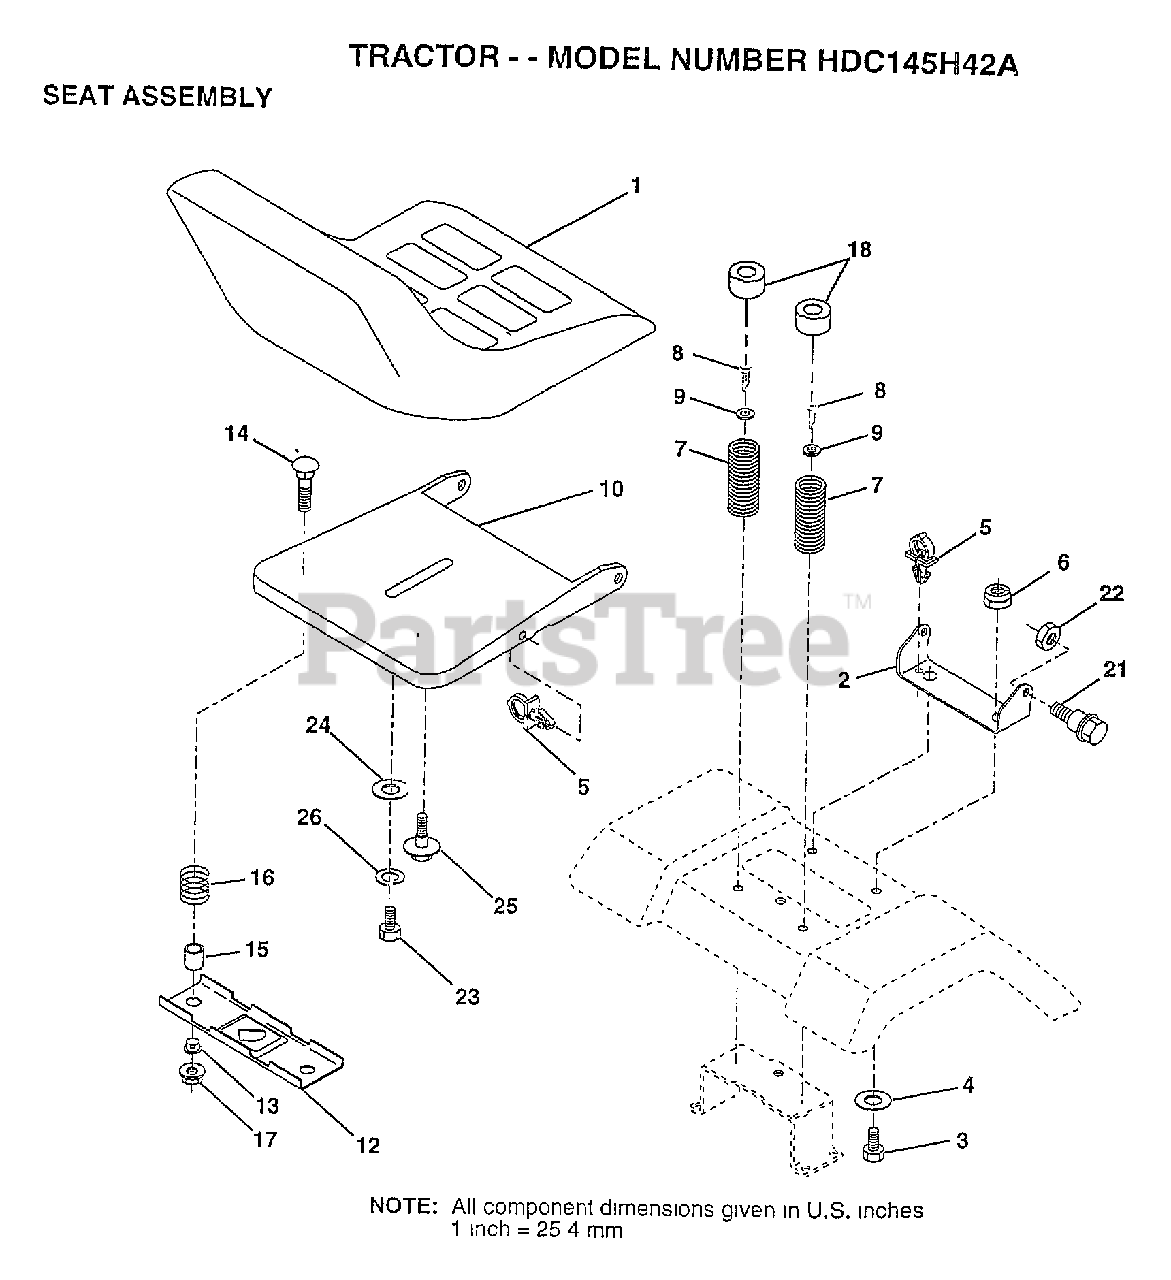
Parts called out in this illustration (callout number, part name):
1	SEAT
2	BRACKET PVT SEAT
3	BOLT
4	WASHER PM
5	CLIP.PUSH-IN.HING
6	NUT
7	SPRING COMPRESSIO
8	SCREW GTV
9	WASHER
10	PAN-SEAT
12	BRKT SWITCH
13	BUSHING
15	SPLIT SPACER
16	SPRING
18	CAP SPRING
21	"BOLT,SHOULDER"
23	BOLT
24	WASHER
25	"BOLT,SHOULDER"
26	LOCKWASHER
